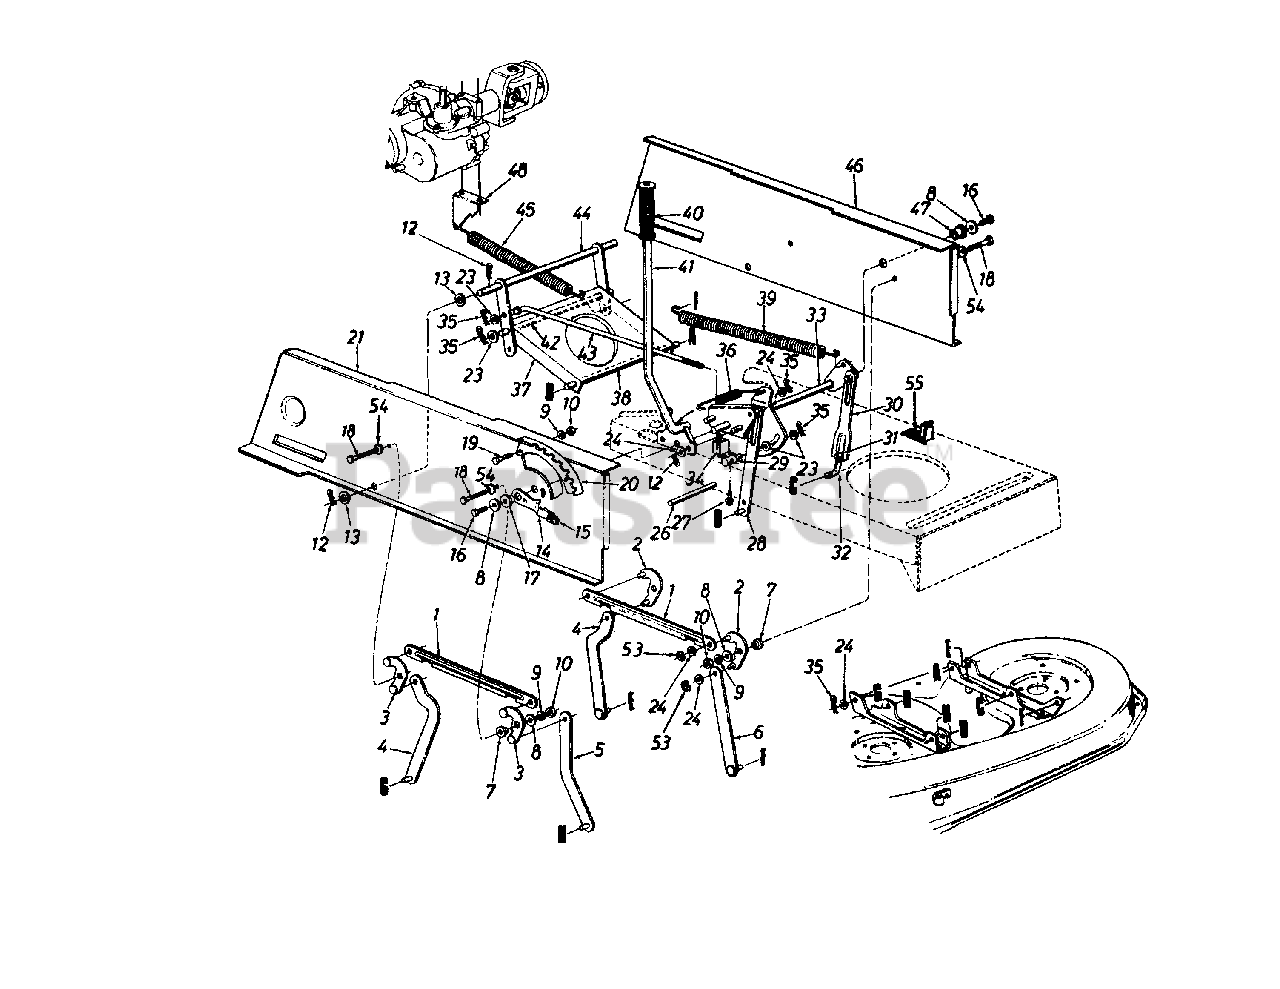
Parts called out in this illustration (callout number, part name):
3	Pivot Link Ass'y.-R.H.
7	Shld. Spacer .318" I.D.
8	Fl-Wash. .344" I.D. x 1.125"
9	L-Wash. 5/16" I.D.
10	Hex Nut 5/16-18 Thd.
12	Cotter Pin 1/8" Dia.
13	Fl-Wash. .635" I.D. x 1.0" O.D.
14	Height Adj. Stop Lever Ass'y.
15	Knob
16	Hex Wash. TT-Tap Scr, 5/16-18 x .75" Lg.
17	Flange Brg. .63" I.D.
18	Hex Wash. Hd. Scr. 5/16-18 x .875" Lg.
19	Hex Bolt 5/16-18 x .75" Lg.
20	Index Brkt.
21	Upper Frame-R.H.
23	Fl-Wash. .385" I.D. x .87" O.D.
24	Fl-Wash. .531" I.D. x .93" O.D.
26	Running Board Rod
27	Truss Mach. Scr. #10 x .5" Lg.
31	Hex Nut 1/2-20Thd. (Gr. 5)
32	Lift Link Adjuster
33	Lift Shaft Ass'y.
34	Safety Switch (Deck)
35	Inter. Cotter Pin 3/8" Dia.
36	Extension Spring
39	Extension Spring
40	Grip (Lift Handle)
43	Disengagement Rod
46	Upper Frame-L.H.
47	Flange Brg. .632" I.D.
53	E-Ring
54	Bell-Wash. .325" I.D.
55	Spring Switch
